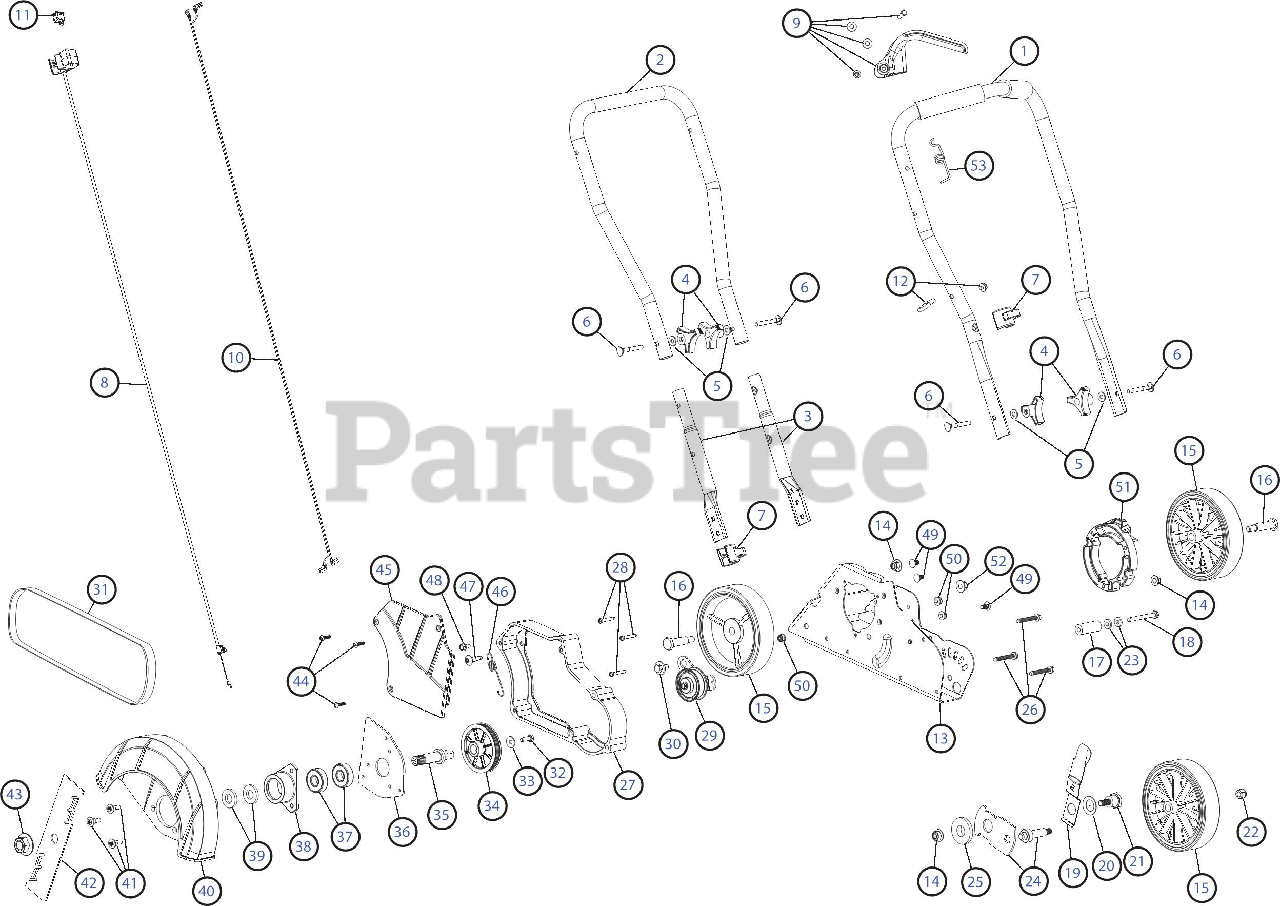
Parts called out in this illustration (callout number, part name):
1	Upper Handle
2	Middle Handle
3	Handle Extension
4	Handle Knob
7	Cable Guide
8	Throttle Cable
9	Throttle Lever w/Hardware
10	WIRE LEAD
11	On/Off Switch
12	Starter Rope Guide
13	Edger Frame
16	Wheel Bolt
18	Spacer Screw
19	PIVOT ARM
21	Shoulder Screw
25	Height Adjustment Spacer
26	Spindle Plate Screw
27	Spindle Spacer
29	Idler Pulley Assembly
30	Shoulder Screw
33	SPRING WASHER BELL
35	Blade Spindle
36	SPINDLE MOUNT PLATE
38	Bearing Cup
39	Washer
40	Blade Guard
45	Belt Cover
49	Bolt
